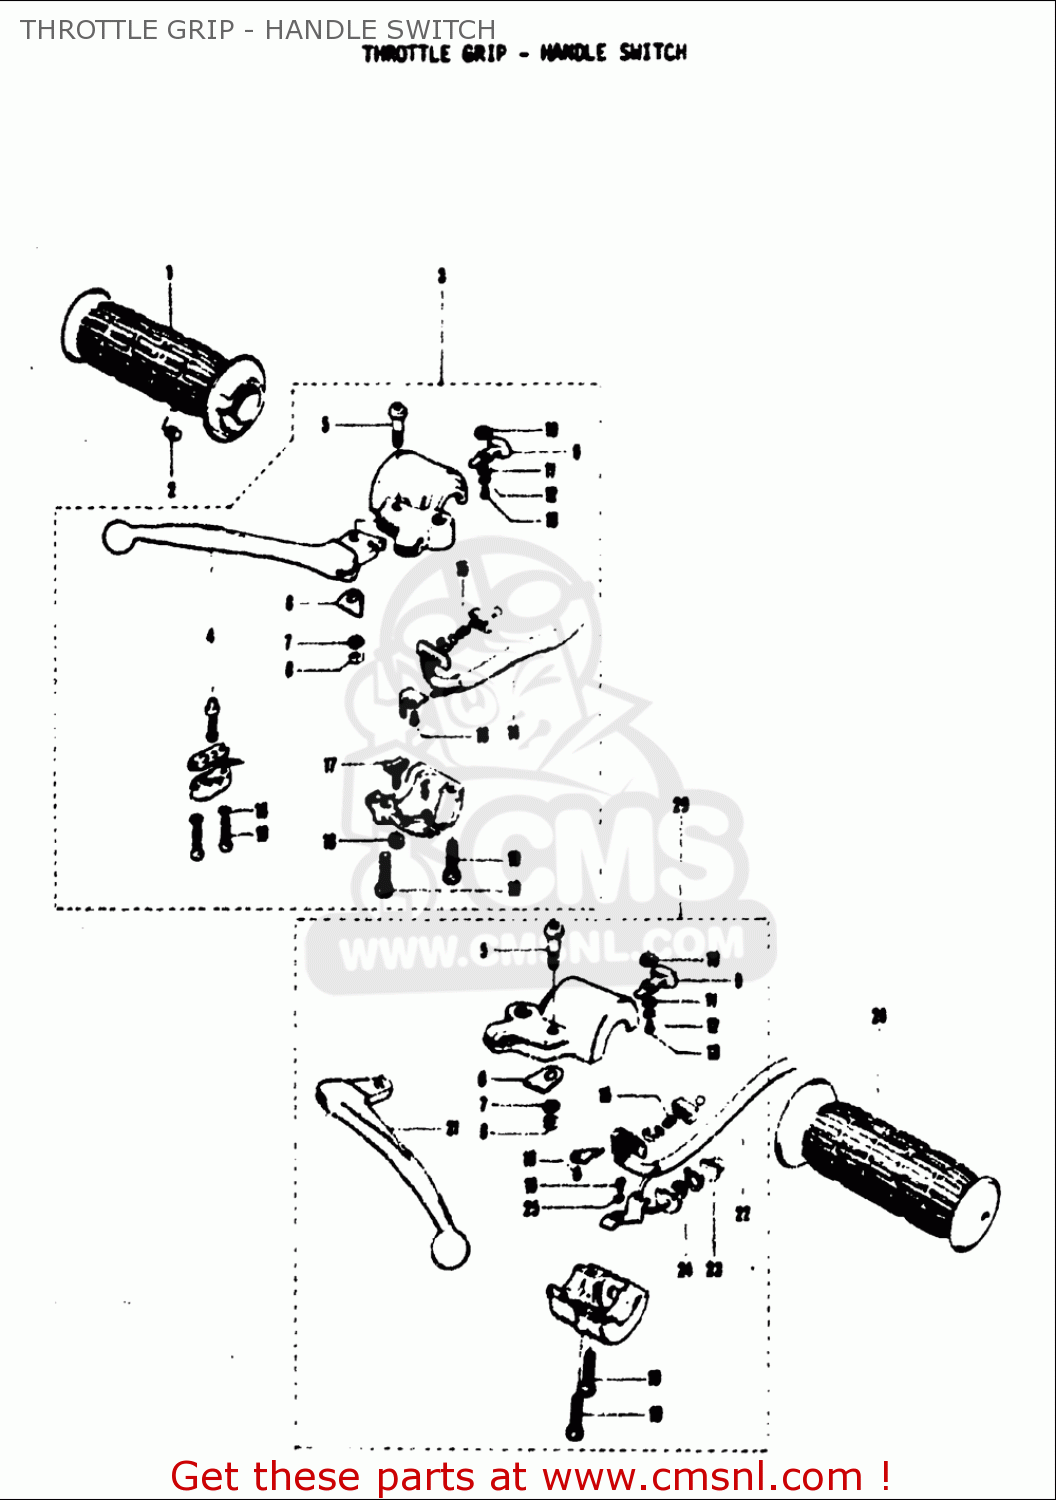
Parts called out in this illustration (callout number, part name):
1	GRIP,THROTTLE
2	PIECE,THROTTLE END
4	LEVER,BRAKE
5	BOLT,LEVER PIVOT
6	SPACER,LEVER
7	WASHER,LOCK
8	NUT
11	WASHER
12	WASHER,LOCK
18	NUT
19	SCREW
21	LEVER,CLUTCH
23	BUTTON
24	SPRING
25	WASHER,LOCK
26	GRIP
